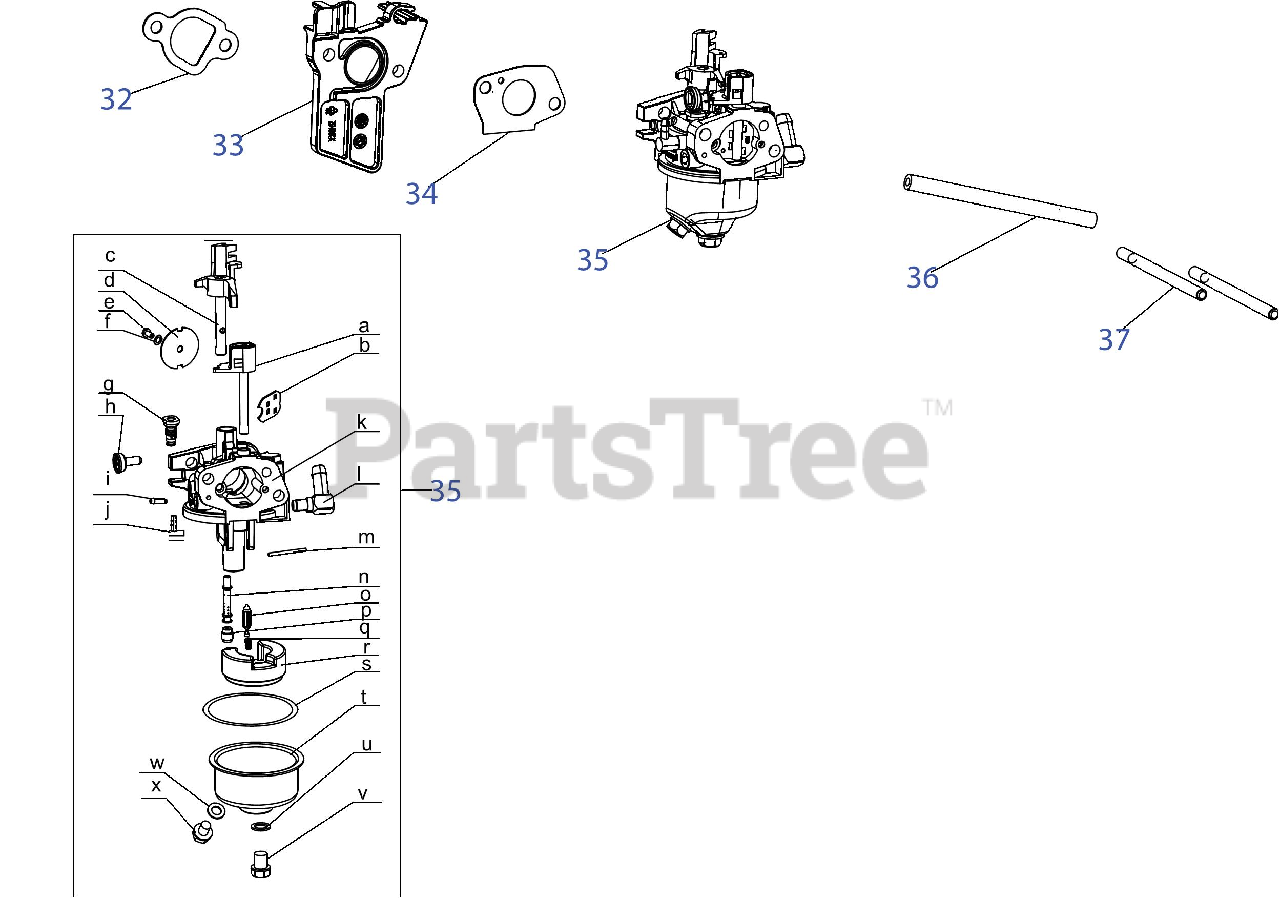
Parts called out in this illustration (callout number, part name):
32	Gasket, Carburetor Insulator
34	Gasket, Carburetor
35	Carburetor
36	Fuel Hose,3.2?6.5?170
37	Stud, M6?92
